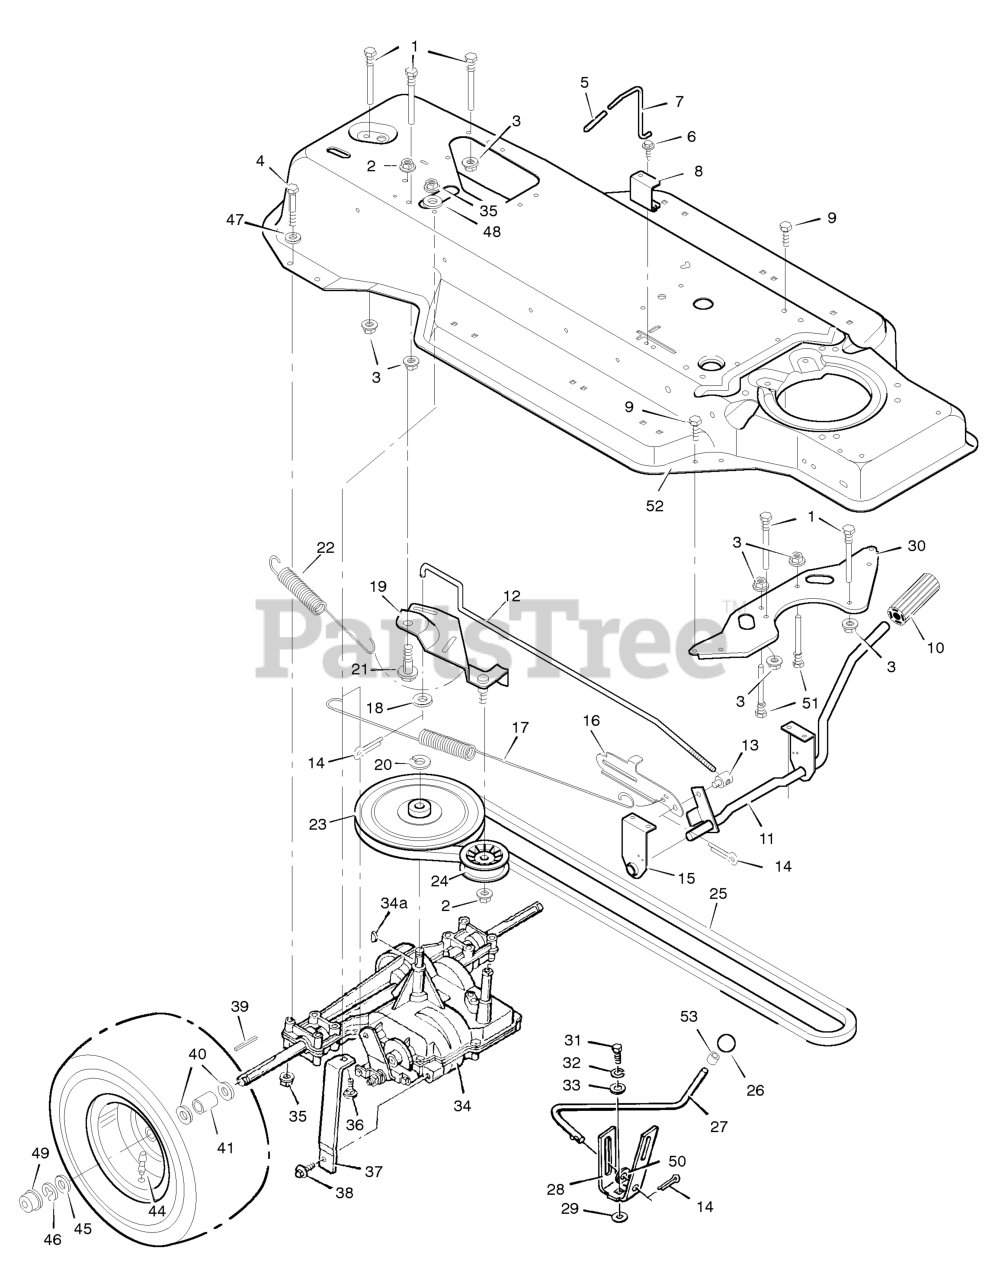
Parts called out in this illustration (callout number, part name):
1	Guide, Belt
2	Locknut, Flange
3	Nut, Flange
4	Bolt, Hex
7	Rod, Control
8	Guide, Bracket
10	Clutch and Brake Pedal
11	Lever Assembly
12	Rod, Clutch
13	Nut, Adjustable
14	Pin, Cotter
15	Bracket, Support
16	Latch, Park Brake
17	Spring, Brake Extension
18	Washer
19	Bracket Assembly, Idler
20	Ring, Retainer
21	Bolt, Shoulder
22	Spring, Drive Extension
23	Pulley, Motion Drive
24	Pulley, Backside Idler
25	Belt, Motion Drive
26	Knob, Shift Lever
27	Lever, Shift
28	Yoke, Shift
30	Plate, Belt Guide
31	Bolt, Hex
32	Lockwasher
34	Transaxle, Peerless **
34A	Woodruff Key No. 9
35	Nut, Flange
36	Bolt, Carriage
37	Support, Transaxle
39	Key, Square
41	Spacer, Transaxle
43	Wheel & Tire Assembly
44	Stem, Valve
47	Washer
49	Hub Cap
50	Washer
51	Guide, Belt
52	Frame Assembly
53	Ring, Tolerance
